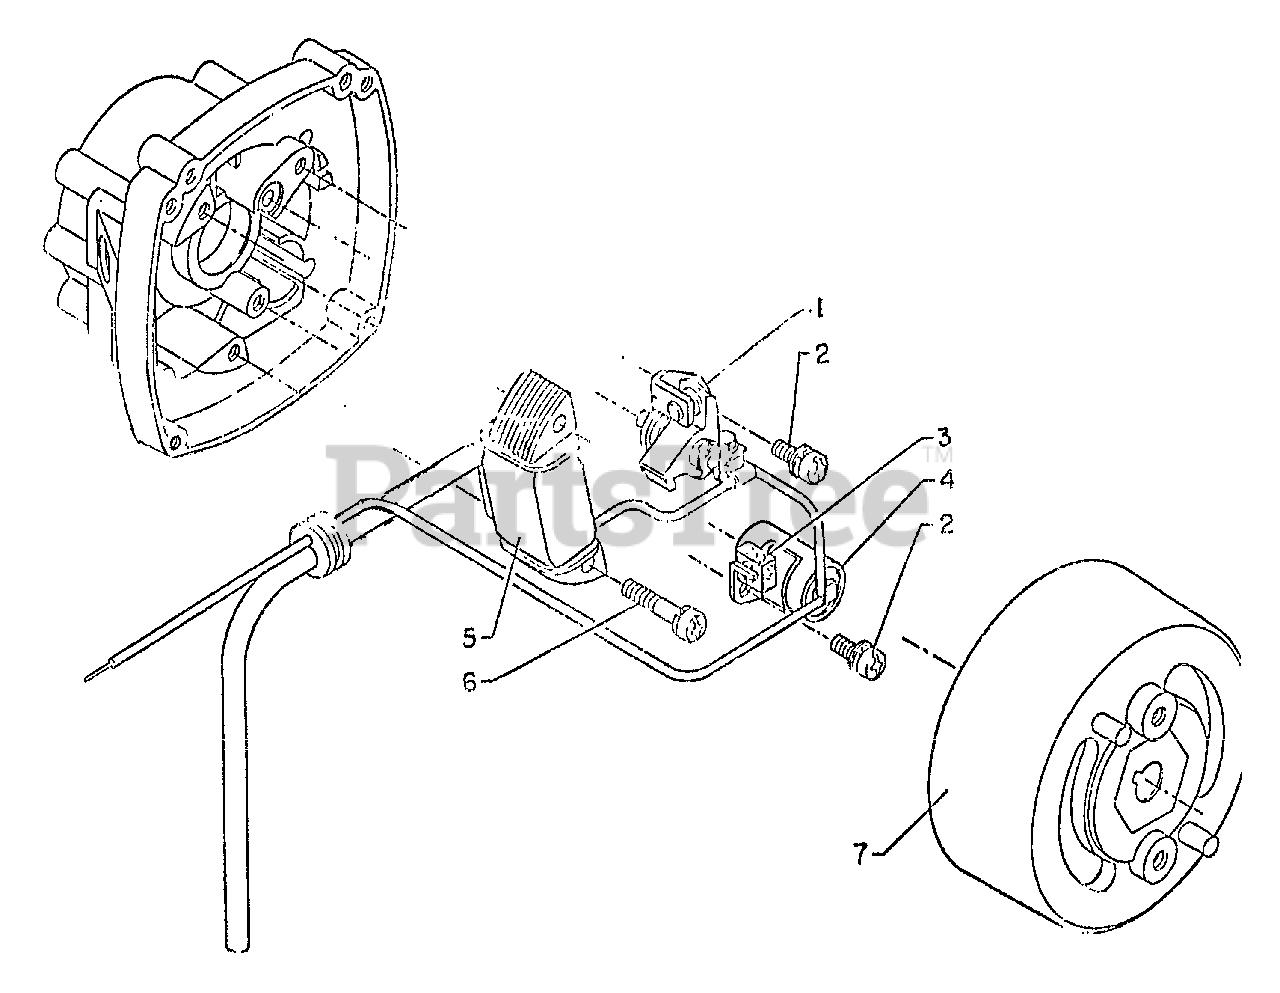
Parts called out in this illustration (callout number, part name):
1	CONTACT POINT SET
2	SCREW 4×10
2	WASHER, SPRING 4 MM
2	WASHER 4 MM
3	PAD, OIL
4	CONDENSER
5	COIL, IGNITION
6	SCREW 4×24
6	WASHER, SPRING 4 MM
7	FLYWHEEL
